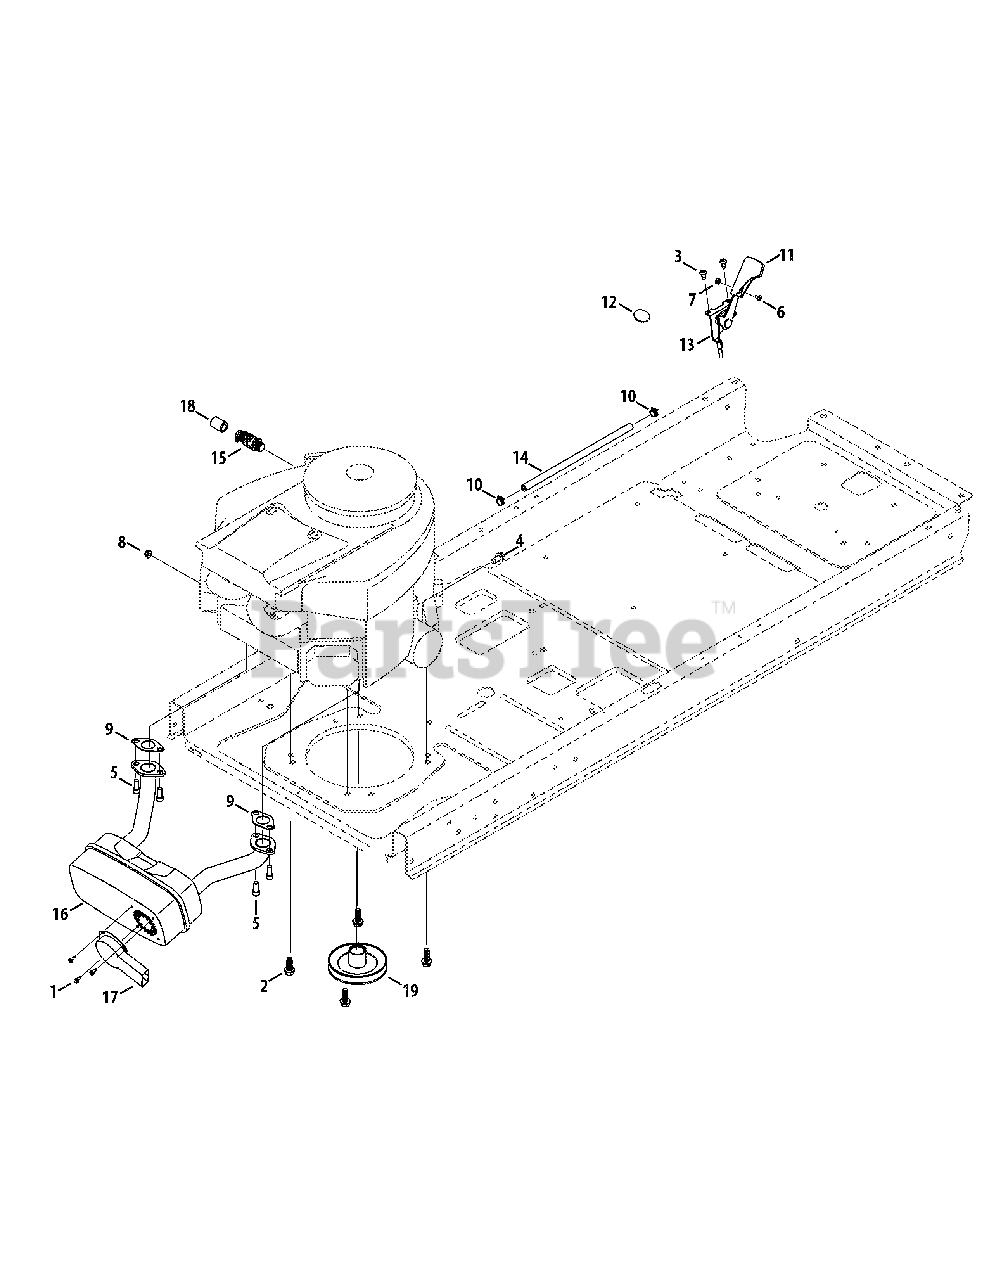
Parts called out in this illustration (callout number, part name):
1	Hex Washer Screw, #8-18 x .500
2	Hex Washer Screw, 3/8-16 x 1.000
3	Screw, 1/4-20 x .5
4	Hex Washer Screw, 1/4-20 x .500
5	Screw, 5/16-18 x .750
6	Machine Screw, #8-32 x .375
7	Hex Nut, #8-32
8	Flange Lock Nut, 1/4-20
9	Exhaust Gasket
10	Hose Clamp, .490
11	Throttle Knob
12	Choke Plug
13	Throttle/Choke Cable
14	Low-Permeation Fuel Hose
15	Oil Drain
16	Muffl er
17	Muffl er Defl ector
18	Oil Drain Extension Hose
19	Engine Pulley
